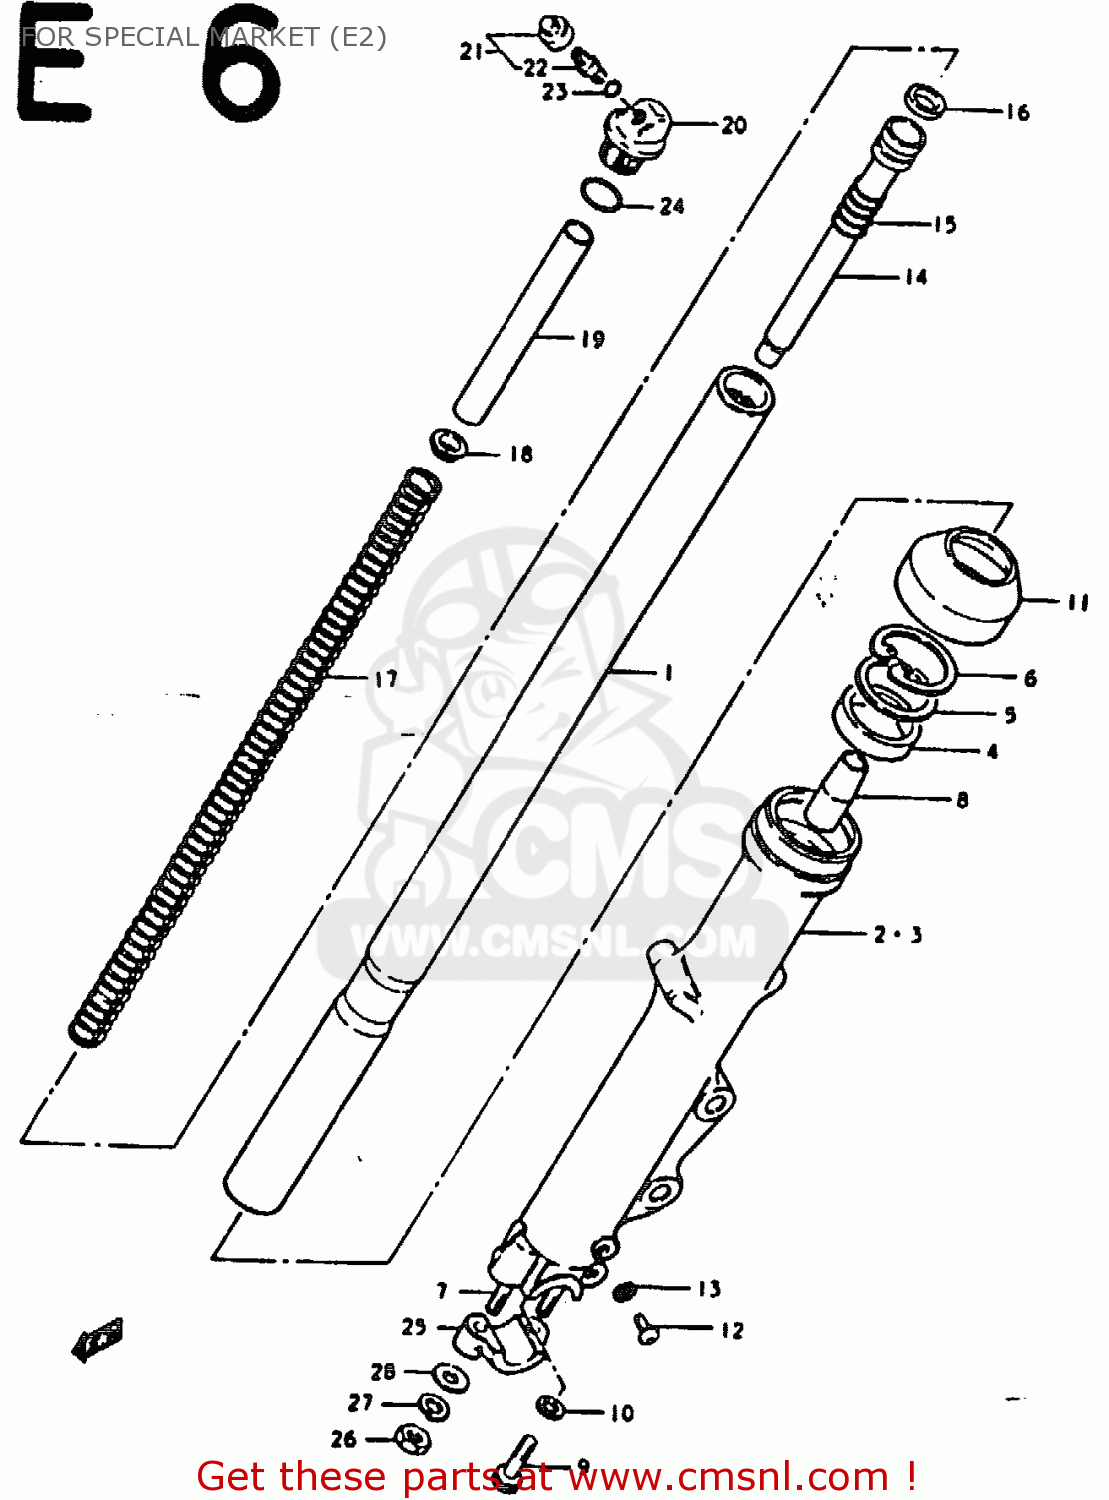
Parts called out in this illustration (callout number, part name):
1	TUBE,FORK,INNER
2	TUBE,FORK,OUTER,RIGHT
3	TUBE,OUTER,LEFT
4	OIL SEAL,FRONT FORK
5	WASHER. FRONT FORK
6	CIRCLIP,FORK OIL SEAL
7	STUD BOLT
8	PIECE,OIL LOCK
9	BOLT,FORK CYLINDER(10X25)
10	GASKET (NAS)
11	SEAL,DUST
12	SCREW
13	GASKET,DRAIN,PLUG (NAS)
14	CYLINDER,FRONT FORK
15	SPRING,REBOUND
16	RING,PISTON
17	SPRING,MAIN
18	GUIDE,FRONT FORK SPRING C
19	SPACER,FRONT FORK SPRING
20	CAP
21	VALVE & CAP ASSY
22	VALVE
23	O RING
24	O RING
25	HOLDER,AXLE
26	NUT (8MM)
27	LOCK WASHER
28	WASHER
